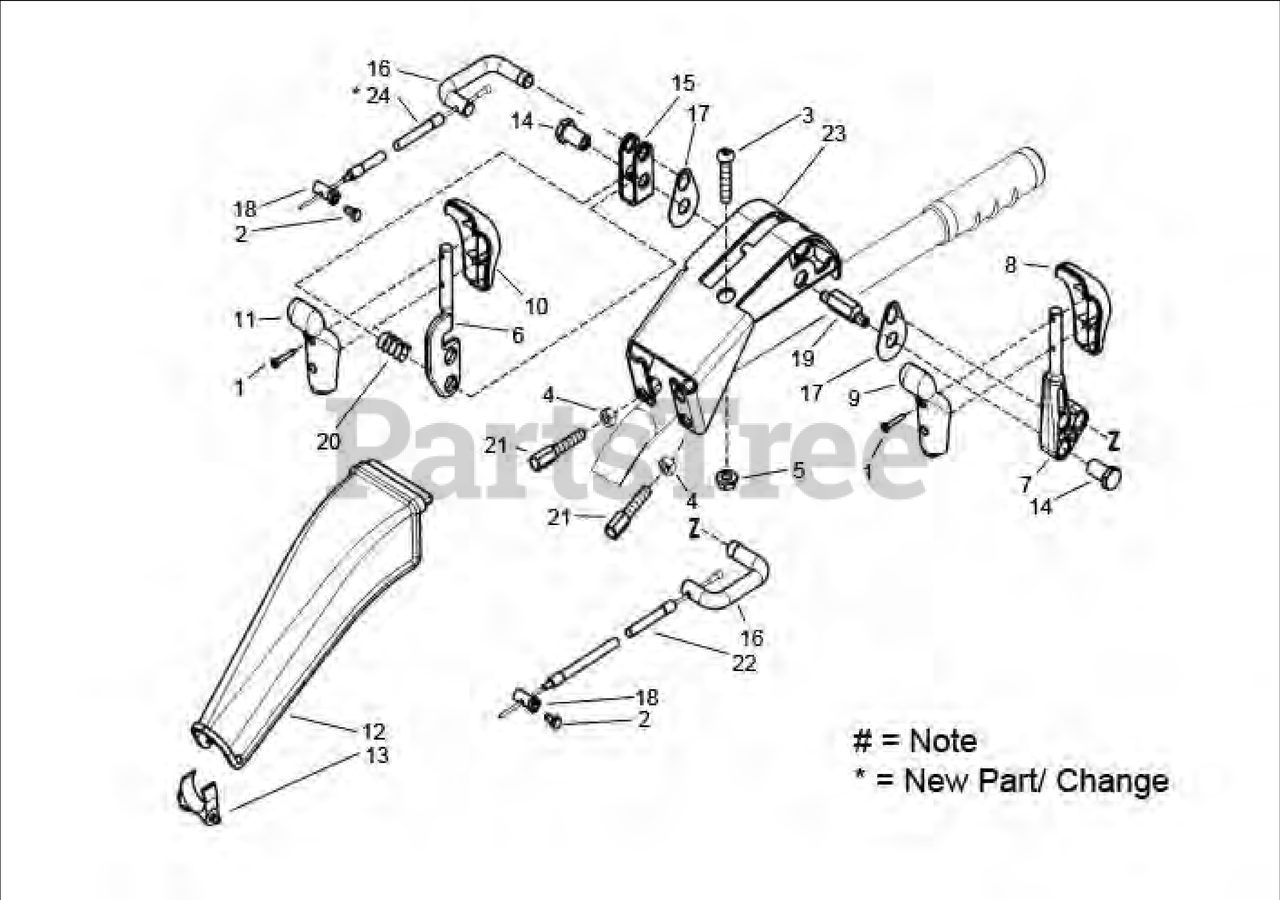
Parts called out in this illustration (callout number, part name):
1	SCREW M5X6
2	CAP SCREW, M6X16
3	SCREW
4	NUT, M8
5	NUT, SELF LOCKING M8
6	LEVER REVERSE
7	LEVER DIFFERENTIAL
8	GRIP UPPER BLACK
9	GRIP LOWER BLACK
10	GRIP UPPER RED
11	GRIP LOWER RED
12	COVER
13	CROSS PIECE
14	BUSHING, REVERSE LEVER
16	ANCHOR PIN
17	PLATE, SMALL
18	CLAMP, CABLE (Cap Screw not included)
20	SPRING
21	CABLE ADJUSTER
22	CABLE (DIFFERENTIAL)
23	SUPPORT BRACKET
24	CABLE (FORWARD / REVERSE)
